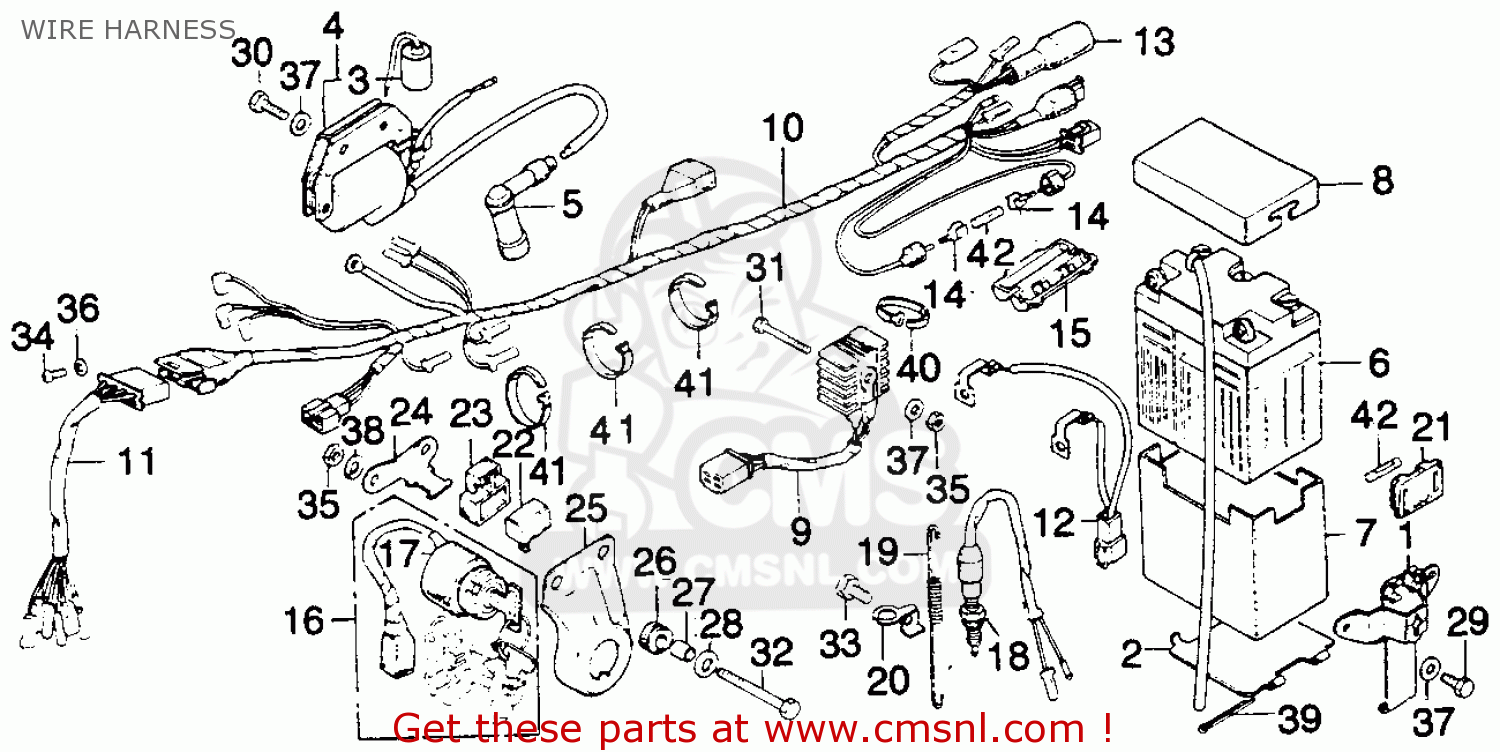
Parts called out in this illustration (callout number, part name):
1	PLATE, BATTERY HINGE
2	PLATE, HINGE HOOK
3	CONDENSER ASSY.
4	COIL, IGNITION
5	CAP
6	BATTERY,6N6
7	COVER A, BATTERY
8	COVER B, BATTERY
9	RECTIFIER ASSY.
10	HARNESS A,WIRE
11	WIRE HARNESS B
12	WIRE
13	CONNECTOR,HARNESS
14	CONNECTOR,FUSE
15	CASE,FUSE CONN.
16	KEY SET
18	SWITCH,STOP LAMP
19	SPRING, STOP SW.
20	STAY, STOP SWITCH
21	CASE,FUSE
22	SIGNAL STAT
23	SUSPENSION,WINKER
24	STAY
25	BRACKET SWITCH
26	RUBBER,CUSHION
27	COLLAR,NO.BRACKET
28	WASHER, HANDLE
29	BOLT,HEX 6X12
30	BOLT,HEX 6X20
31	BOLT,HEX 6X36
32	BOLT,HEX 6X45
33	BOLT HEX,8X10
34	SCREW,4X8
35	NUT HEX 6MM
36	WASHER,4MM
37	WASHER PLAIN 6MM
38	WASHER,SPRING,6MM
39	PIN COTTER 3.0MM
40	BAND,BI WIRE
41	BAND A3,WIRE
42	FUSE,10A,25MM
